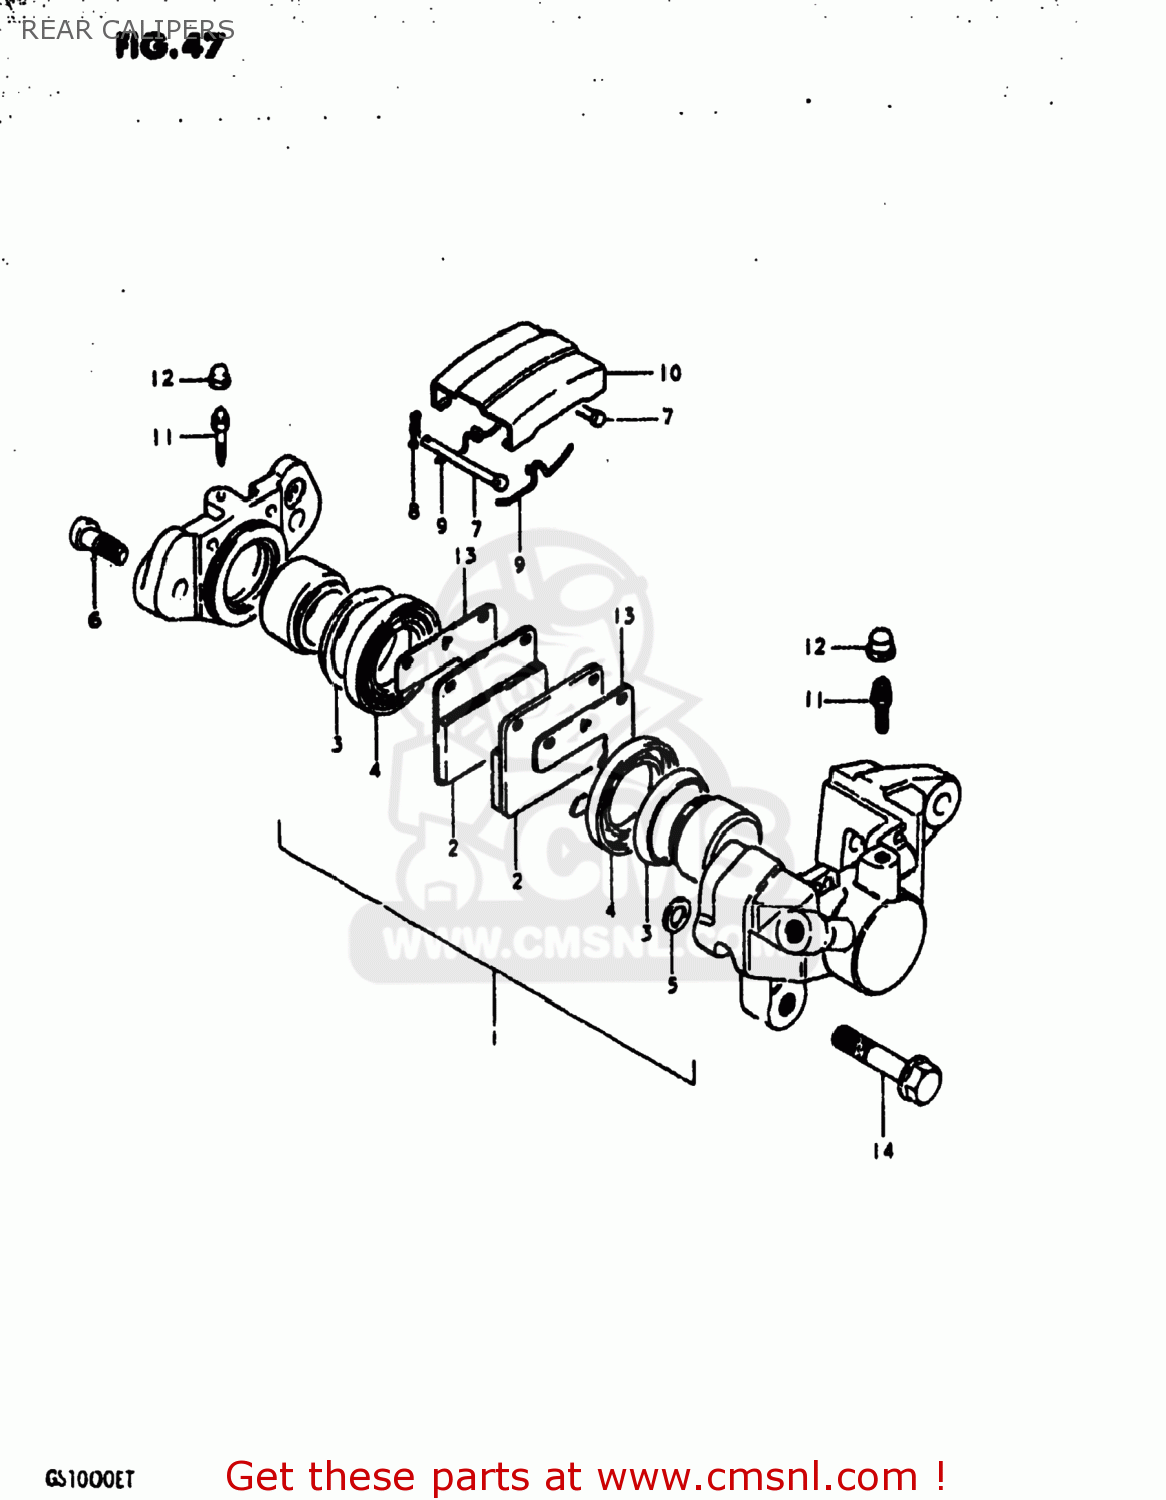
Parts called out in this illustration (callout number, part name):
1	PISTON SET
2	PAD,BRAKE
3	SEAL,PISTON
4	BOOT,PISTON
5	SEAL,PISTON
6	BOLT,HOUSING
7	PIN,PAD
8	CLIP,PAD PIN
9	SPRING
10	COVER,DUST
11	BLEEDER
12	CAP,BREATHER
13	SHIM,RR CALIPER
14	BOLT
